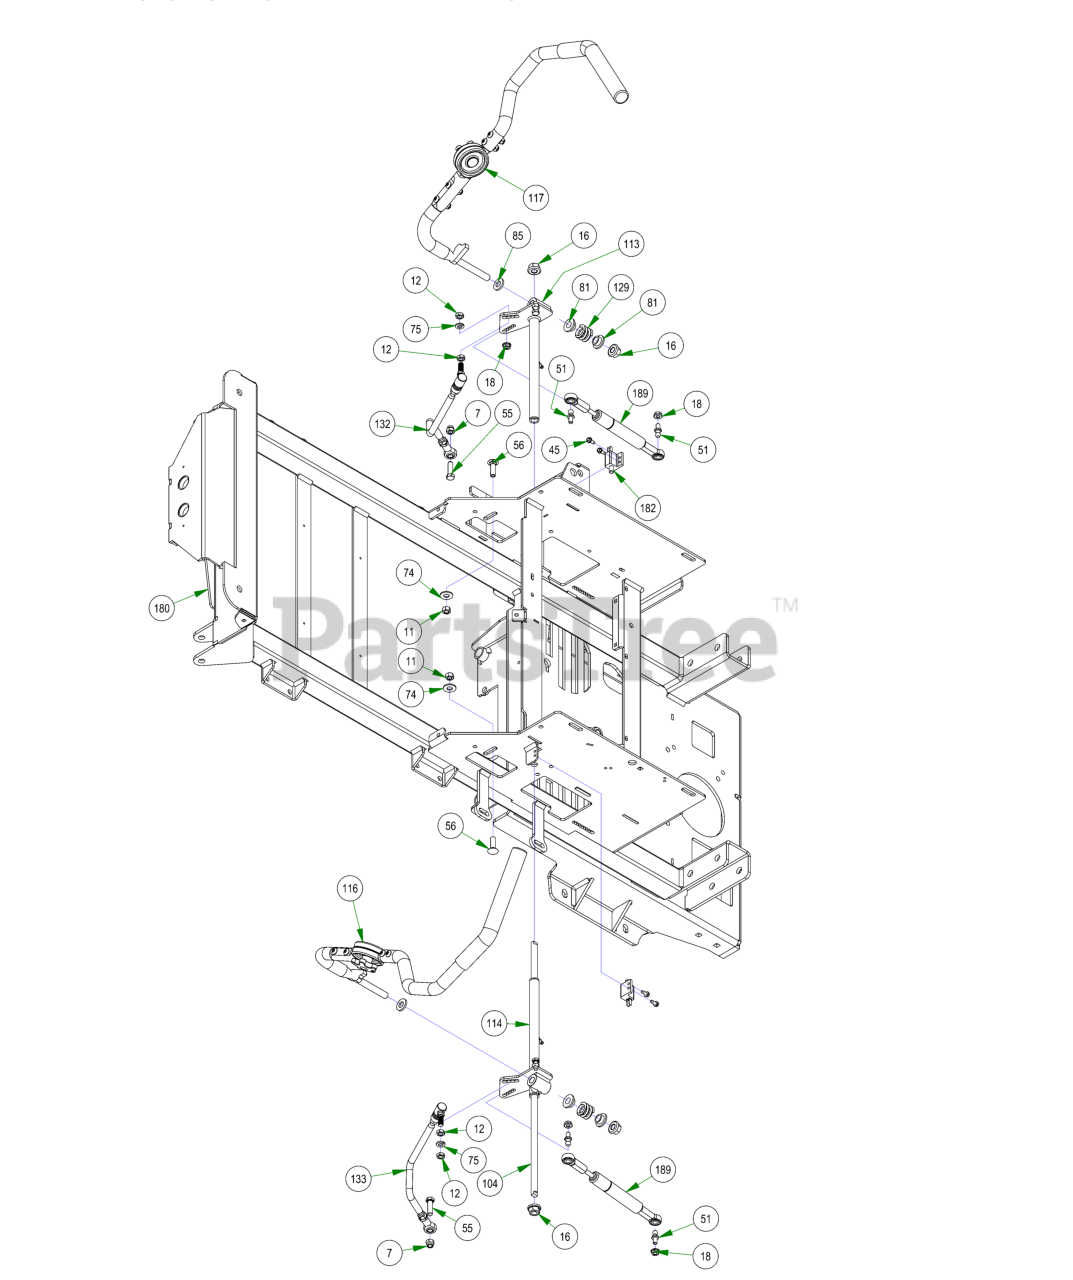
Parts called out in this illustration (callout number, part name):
7	3/8-16 NYLON INSERT LOCKNUT ZINC
11	3/8-16 HEX NUT ZINC
12	3/8-24 HEX NUT ZINC YELLOW
16	1/2-13 NYLON INSERT FLANGE LOCKNUT ZINC
18	5/16-18 HEX SERRATED FLANGE NUT HARD/ZINC
45	12-24 X 1/2 HEX WASHER UNLSOT F TCS ZINC
51	10mm Damper Ball Stud-Steering
55	3/8-16 X 1-1/4 HEX CAP SCREW (GR.5) ZINC
56	3/8-16 X 1-1/4 CARRIAGE BOLT ZINC
74	3/8 FLAT WASHER USS (1" OD) ZINC
75	3/8 SPLIT LOCKWASHER ZINC
81	.525 ID SHOULDER WASHER NYLON
85	.505 ID X 1.000 OD X .125 THICK FLAT WASHER NYLON
104	2021 Maverick Steering Actuator Rod
113	2021 Maverick Drive Arm Actuator RH Assembly
114	2021 Maverick Drive Arm Actuator LH Assembly
116	2018 Adjustable Steering Arm - Left
117	2018 Adjustable Steering Arm - Right
129	Drive Lever Spring
132	Push Rod-Right
133	Push Rod-Left
180	2022 Maverick Frame - Painted
182	Safety Switch
189	Steering Damper
